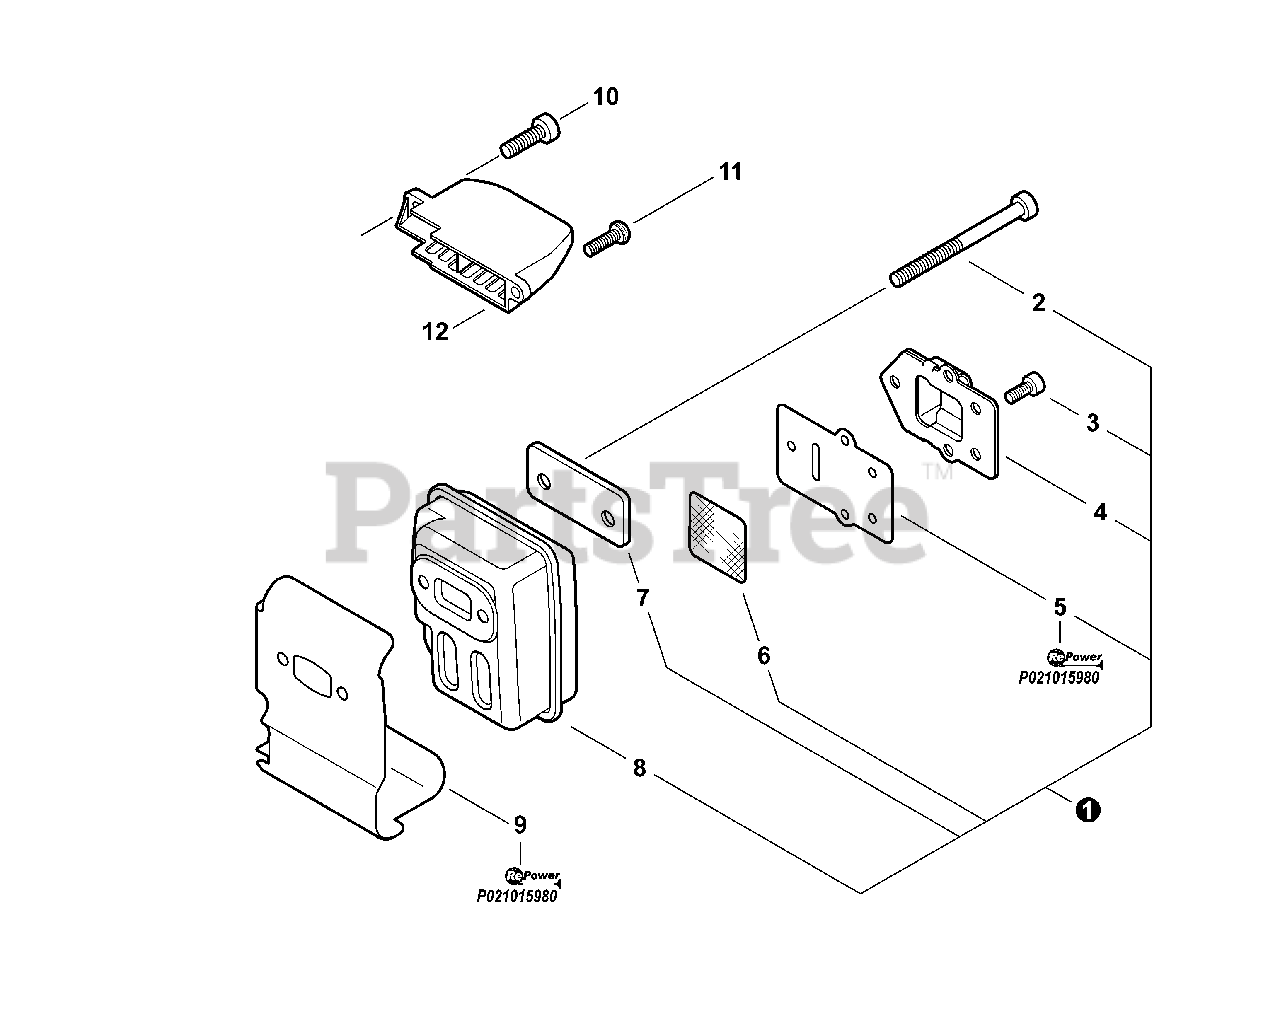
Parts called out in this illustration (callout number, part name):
1	MUFFLER ASSY
2	BOLT, TORX 5×55
3	BOLT, TORX 4×8
4	GUIDE, EXHAUST
5	GASKET, EXHAUST
6	SCREEN, SPARK ARRESTER
7	PLATE, EYE
8	MUFFLER
9	HEAT SHIELD, EXHAUST
10	BOLT, TORX 5×16
11	BOLT, TORX 5×16
12	COVER, MUFFLER
